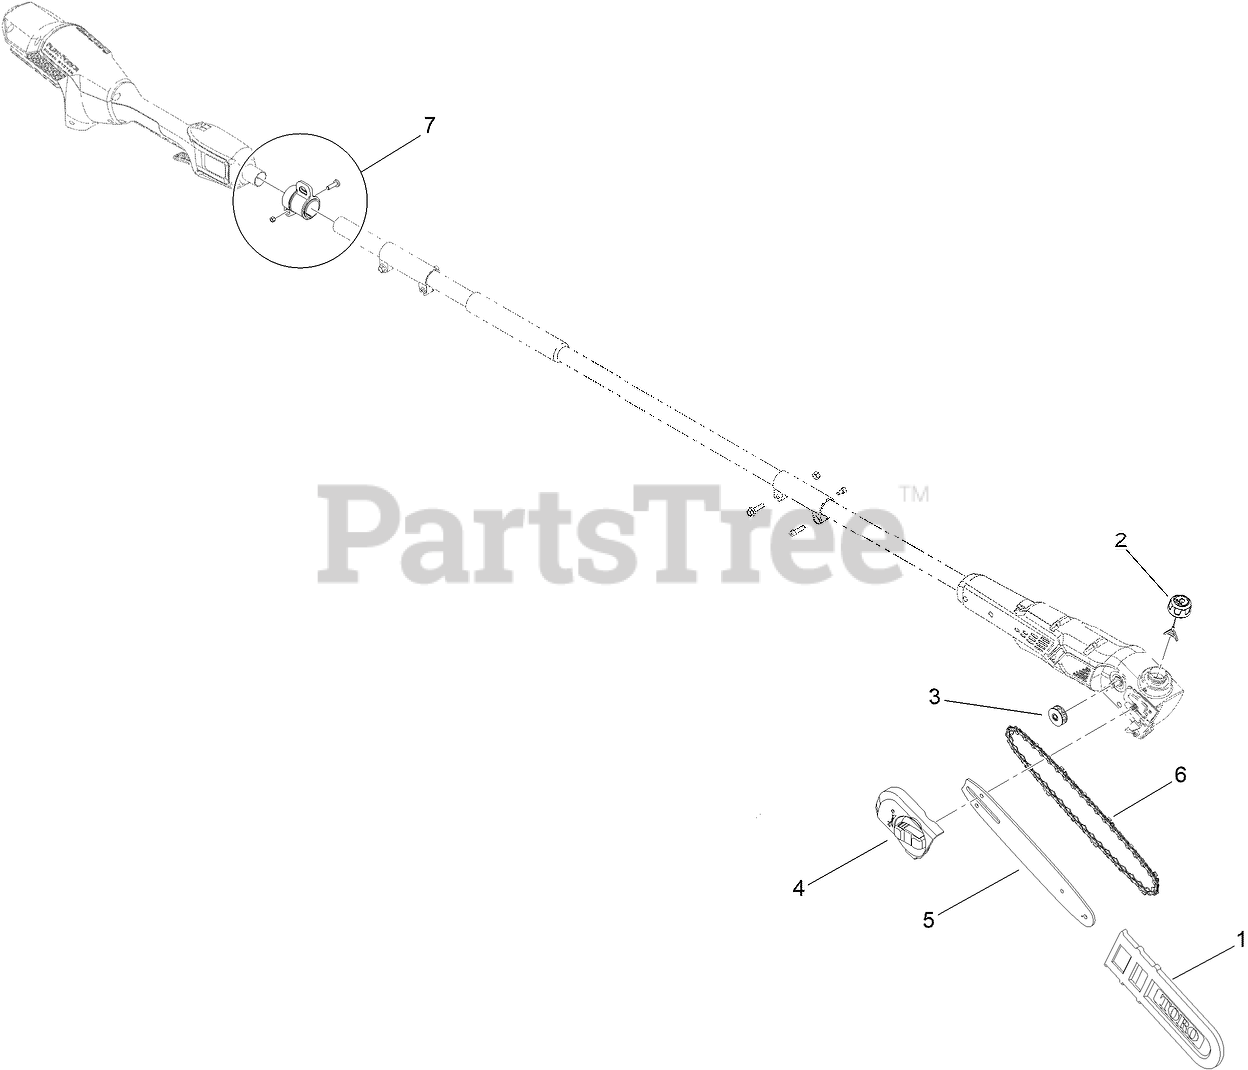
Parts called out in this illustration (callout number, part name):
1	SCABBARD
2	CAP-OIL TANK
3	GEAR-CHAIN DRIVE
4	COVER-CHAIN
6	CHAIN
7	COLLAR-STRAP
